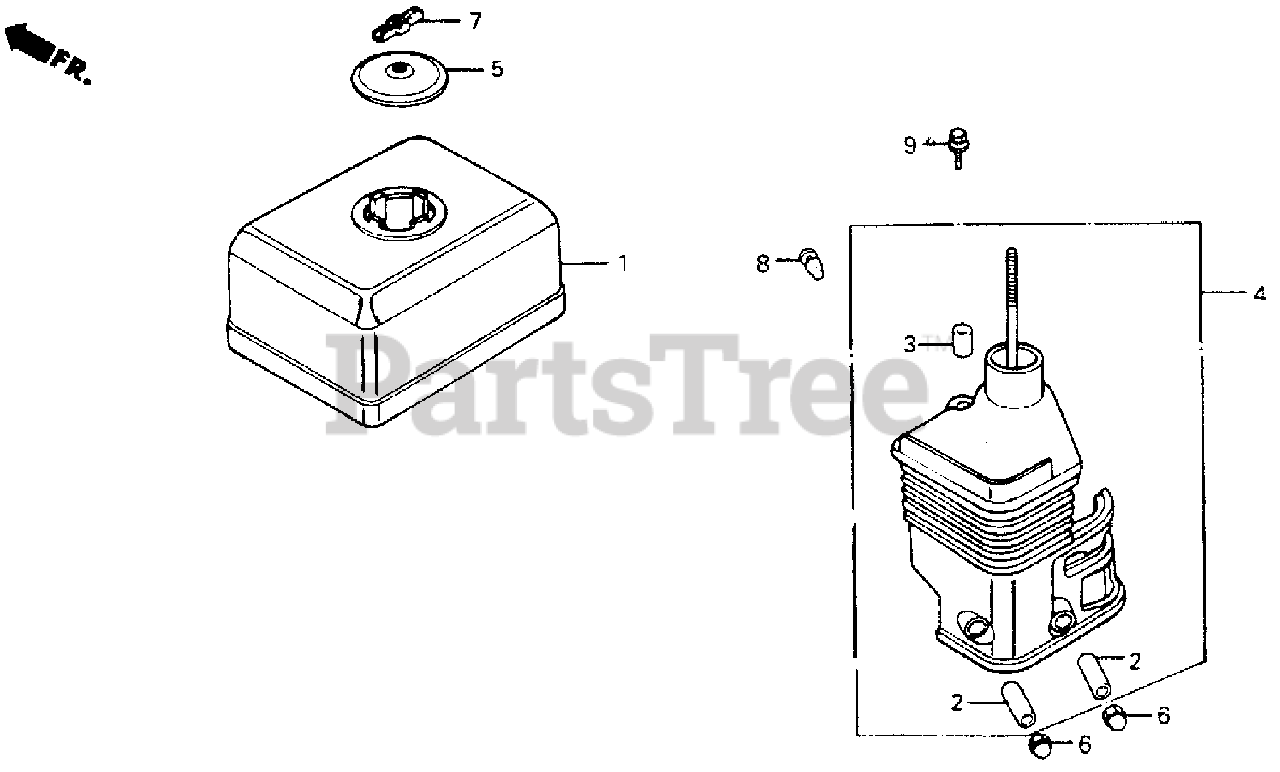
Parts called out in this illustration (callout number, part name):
1	COVER, AIR CLEANER (SEMI-DRY)
2	COLLAR, AIR CLEANER
3	COLLAR B, AIR CLEANER
4	ELBOW, AIR CLEANER
5	CAP, CLEANER
6	NUT, CAP (6MM)
7	WINGNUT, AIR CLEANER COVER
8	PLUG, CONE TYPE
9	BOLT-WASHER (6X20)
